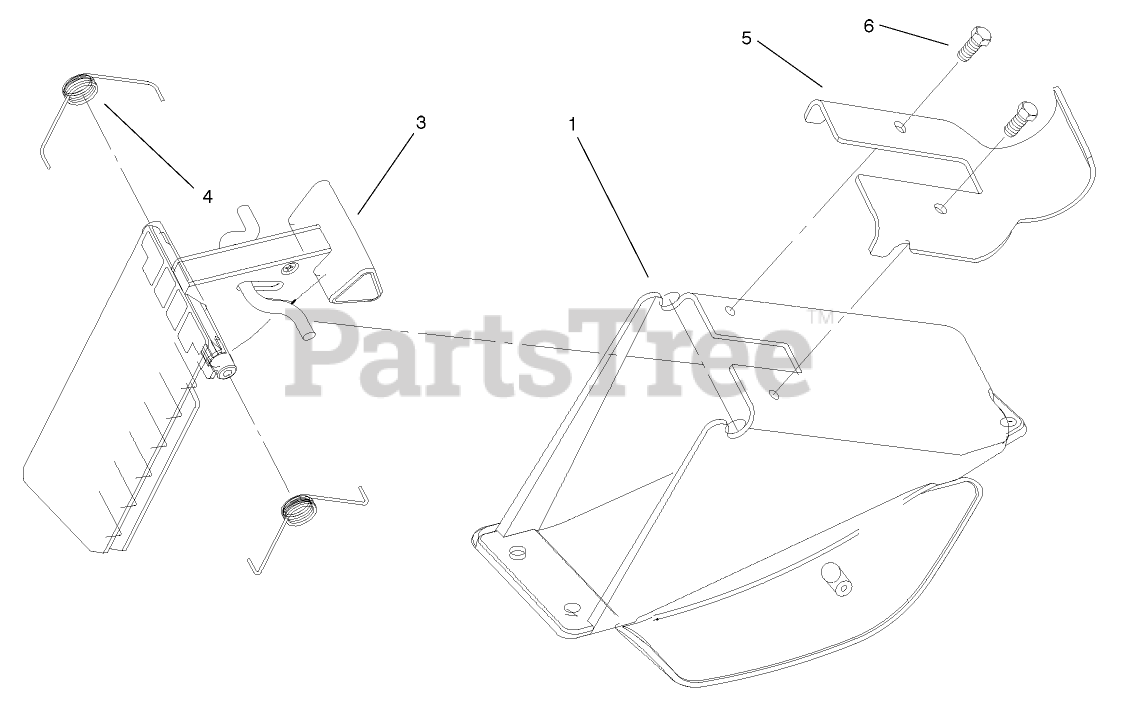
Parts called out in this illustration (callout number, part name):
3	ASM - DISCHARGE DOOR
4	SPRING-DOOR, RH
5	CHUTE PLATE ASM
6	SCREW-PLASTITE
